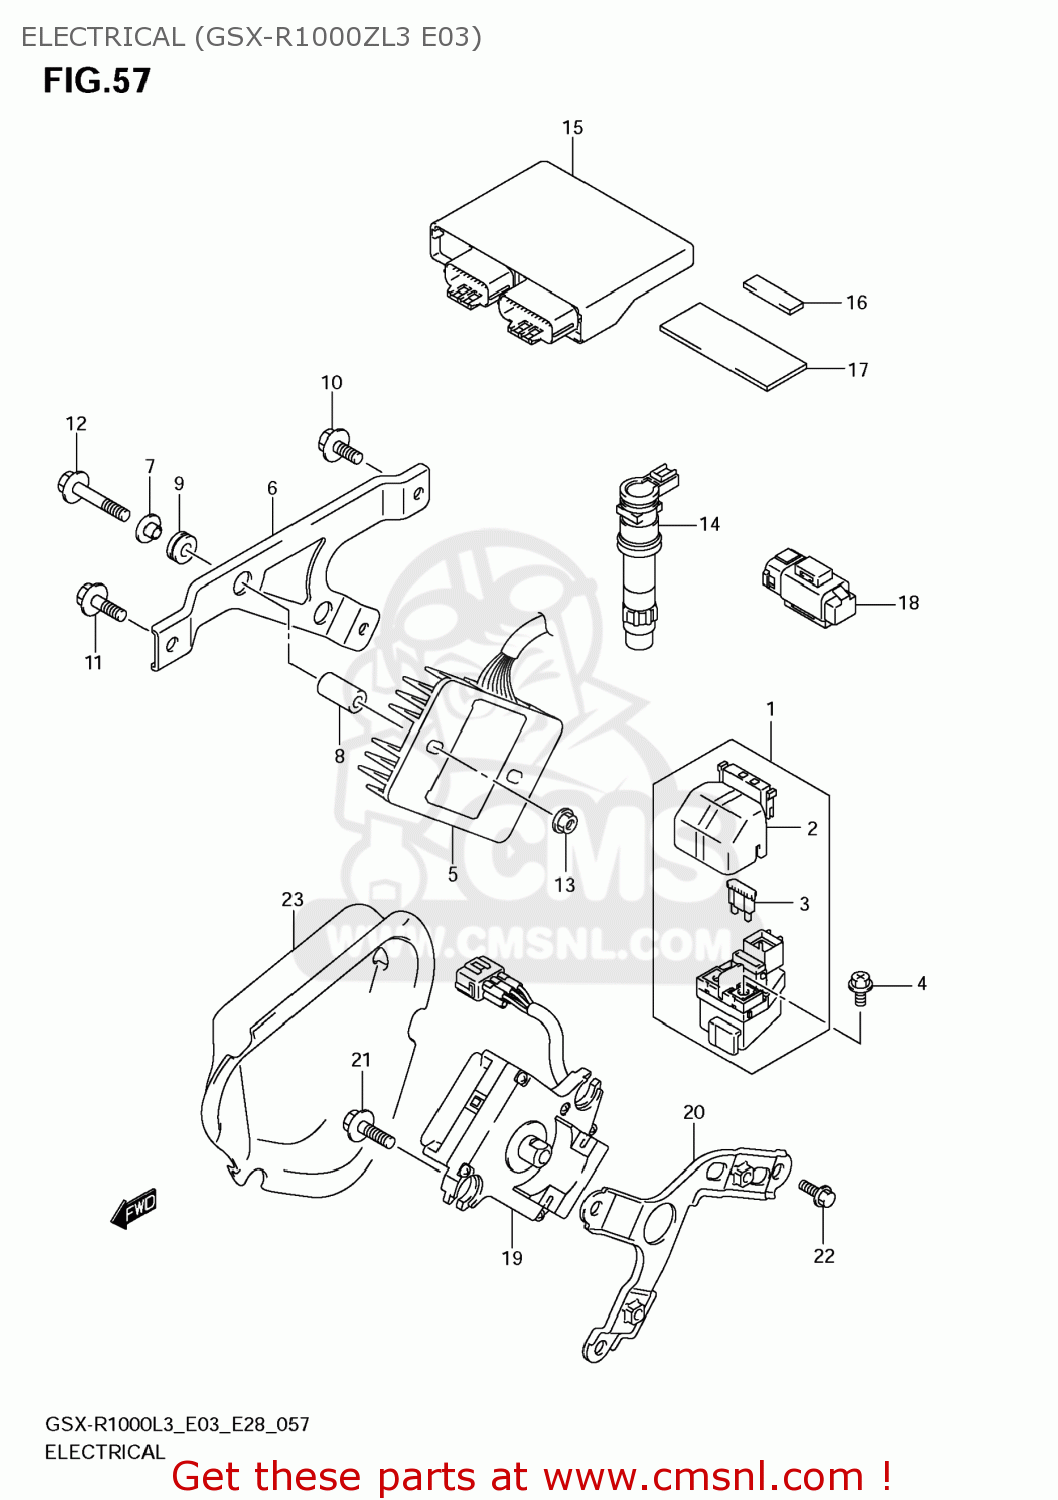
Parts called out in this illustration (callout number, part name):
1	RELAY ASSY,STARTING MOTOR
2	COVER
3	FUSE(30A)
4	SCREW(6X8)
5	RECTIFIER ASSY
6	BRACKET,RECT FTG
7	SPACER(6.2X8.4X6.9)
8	SPACER(6.2X14.5X26)
9	CUSHION
10	BOLT
11	BOLT(6X20)
12	BOLT
13	NUT
14	COIL ASSY,IGNITION
15	CONTROL UNIT,FI
16	CUSHION,FI CONTROL UNIT
17	PROTECTOR(30X80X2)
18	SENSOR ASSY,FUEL CUT
19	ACTUATOR ASSY,EXHAUST CONTROL
20	HOLDER,ACTUATOR
21	BOLT(6X25)
22	BOLT
23	COVER,ACTUATOR
